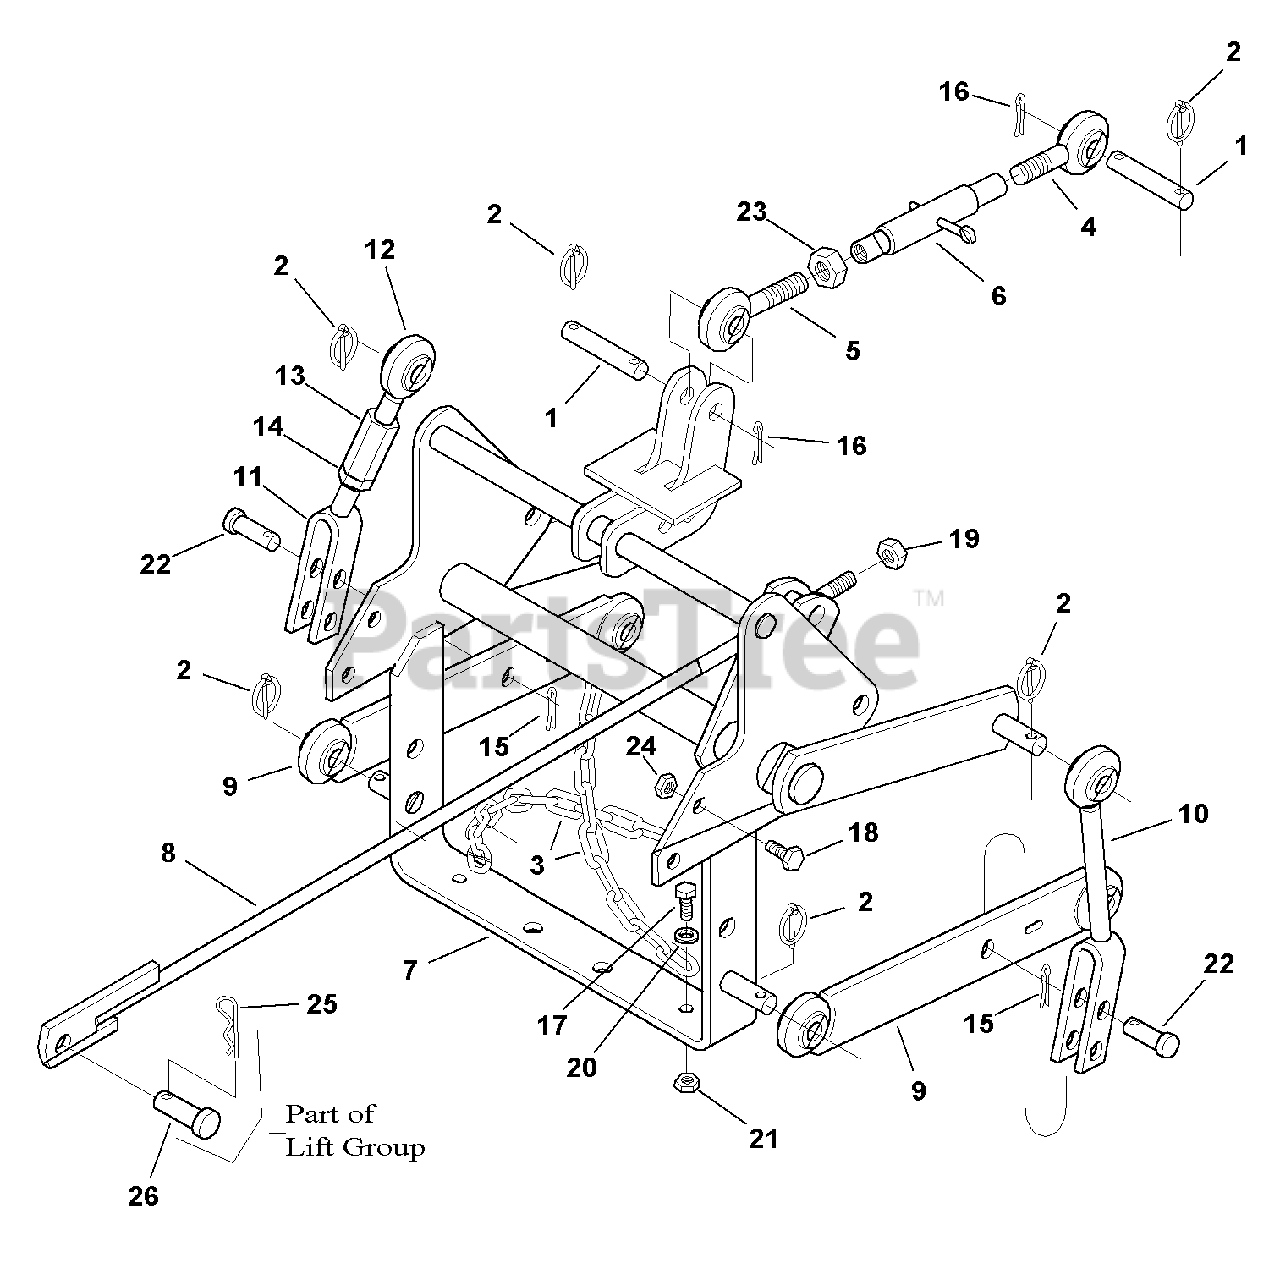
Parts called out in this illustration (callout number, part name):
2	PIN & RING ASSEMBLY
4	STUD & BALL JOINT ASSEMBLY, L.H. Thread
5	STUD & BALL JOINT ASSEMBLY, R.H. Thread
6	TUBE & PIN ASSEMBY
7	HITCH ASSEMBLY
8	LIFT ROD ASSEMBLY
9	BALL JOINTS & LINK ASSEMBLY
10	CLEVIS & BALL JOINT ASSEMBLY, L.H.
11	CLEVIS & STUD ASSEMBLY, R.H. Lower
12	BALL JOINT & STUD ASSEMBLY, R.H. Upper
13	TURNBUCKLE, Hex
14	NUT, Hex Jam, 5/8 -18
15	PIN, Cotter, 1/4 x 1
16	PIN, Cotter, 1/4 x 1-1/2
17	CAPSCREW, Hex Head, 3/8-16 x 1-1/4
18	CAPSCREW, Hex Head, 1/2-13 x 2
19	LOCKNUT, 1/2-13
20	WASHER, 3/8
21	LOCKNUT, 3/8
23	NUT, Hex Jam, 3/4-10
24	NUT, Nylock, 1/2-13
26	PIN, King, 1/2 x 2-1/2
